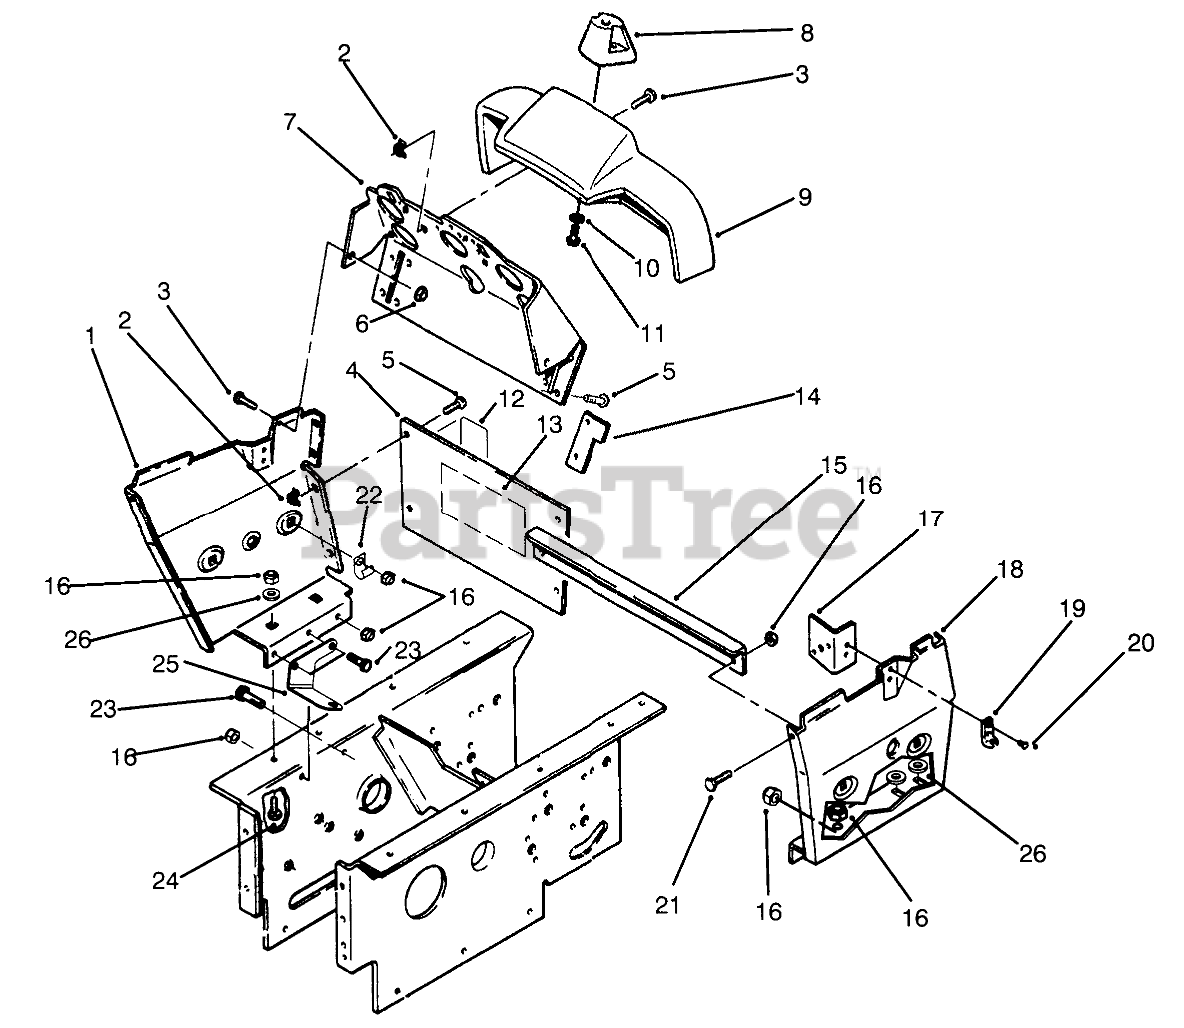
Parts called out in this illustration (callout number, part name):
1	Panel-RH
2	NUT-RETAINED
3	Screw
4	Plate-Hoodstand, Rear (Incl. Ref. #13)
5	Screw
6	NUT-HF
7	ASM-Panel
8	COVER-STEERING SHAFT
9	COVER-CONSOLE 5 GAGE
10	SWIVEL JACK
11	SCREW-#6 PLASTITE
12	DECAL PTO CLUTCH
13	DECAL - DANGER
14	STOP-CHOKE
15	STIFFENER-PANEL B
16	NUT-LOCK, NI
17	BRACKET-SWITCH SU
18	Panel-LH
19	KEEPER-LATCH
20	RIVET-POP
21	SCREW-HH
22	CLIP
23	SCREW-HH
24	CARRIAGE BOLT -4
25	Bracket-Control
26	WASHER-PLAIN
